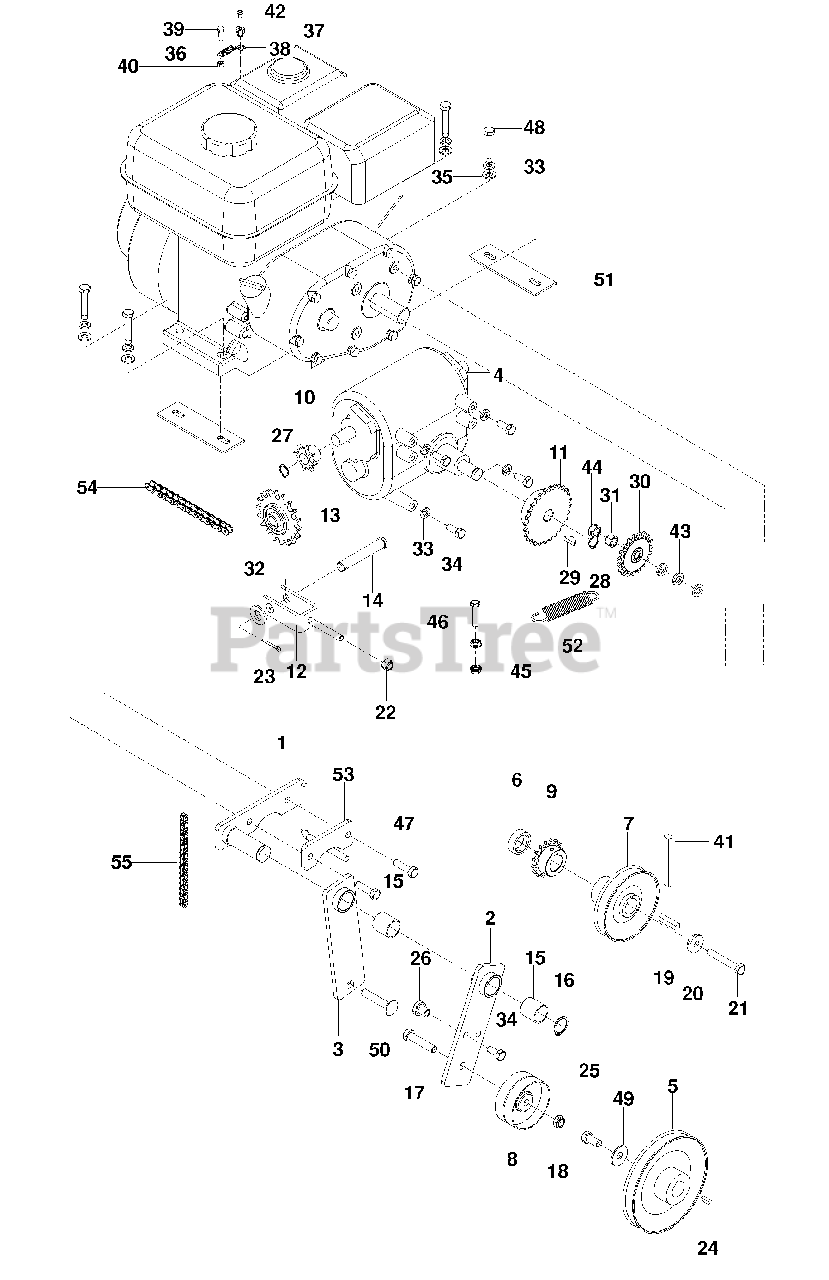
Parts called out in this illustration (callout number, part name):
1	PIVOT, IDLER
2	ARM, IDLER, BELT
3	ARM, IDLER, CHAIN
4	TRANSMISSION, 4 SPEED
5	PULLEY, 5.25 A
6	SPACER, PTO SHAFT
7	PULLEY, 3.75 A
8	PULLEY IDLER
9	SPROCKET, ENGINE
10	SPROCKET #40 CHAIN
11	SPROCKET
12	CHAIN TENSIONER, BLACK
14	PIN CLEVIS 1/2 x 3
16	RETAINING RING
17	HCS 3/8-18 x 1 3/4
18	NUT 3/8-16 HAM NYLOC
19	KEY 7mm SQ x 33mm
20	WASHER, STEPPED
21	HCS M8-1.25 x 55 GR 8.8
22	NUT 5/16-18 NYLOC
23	PIN COTTER 1/8 x 1
24	KEY WOODRUFF #6
25	HCS 3/8-24 x 3/4
26	SPRING ANCHOR
27	RING 9/16 RETAINING, EXT
28	RETAINING RING
29	KEY, WOODRUFF #9
30	SPROCKET, 35 PITCH
31	NUT 3/8-16 NYLOC
32	WASHER 1/2 SAE
33	WASHER 5/16 SLW
34	HCS 5/16-18 x 3/4
35	WASHER 5/16 SAE
36	SPRING, THROTTLE
37	CLAMP, THROTTLE CABLE
38	E-RING CLIP, THROTTLE
39	HCS M5-0.8 x 16 GR 8.8
42	SCREW #8-32 x 1/4
43	WASHER 3/8 SPLT LOCK
44	NUT 3/8-16 CNTRLK
45	NUT 1/4-20 FLANGE LK
46	HCS 1/4-20 x 1 1/4
47	HCS M8-1.25 x 30 GR 8.8
48	HCS 5/16-18 x 1 3/4
49	WASHER 3/8 SPRING
50	RHSNB 3/8-16 x 2
51	PLATE, ENGINE
53	KEEPER, CHAIN
54	CHAIN, TRANSMISSION #35
55	CHAIN, #40
